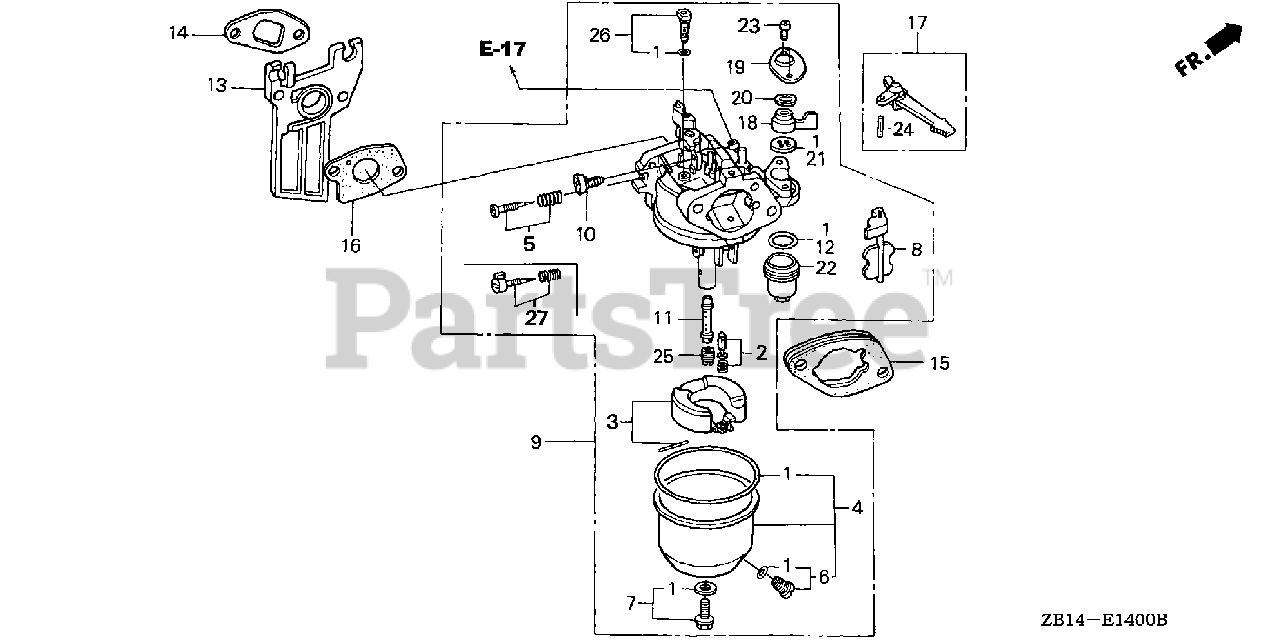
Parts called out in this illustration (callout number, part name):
1	GASKET SET
1	GASKET SET (CARBURETOR NO.)
2	VALVE SET, FLOAT
4	CHAMBER SET, FLOAT (CARBURETOR NO.)
5	SCREW SET, PILOT
6	SCREW SET, DRAIN (CARBURETOR NO.)
7	SCREW SET
9	CARBURETOR ASSY. (N/A: SEE COMPONENTS)
9	CARBURETOR ASSY.
10	SCREW, THROTTLE STOP
11	NOZZLE, MAIN (NOT AVAILABLE)
12	GASKET, FUEL STRAINER CUP
13	INSULATOR, CARBURETOR
14	GASKET, INSULATOR
15	SPACER, CARBURETOR
16	GASKET, CARBURETOR
17	LEVER, CHOKE (STD)
18	LEVER, VALVE
19	PLATE, LEVER SETTING
20	SPRING, PETCOCK LEVER (CARBURETOR NO.)
21	GASKET, PETCOCK (CARBURETOR NO.)
22	CUP, FUEL STRAINER
23	SCREW, PAN (3X8)
23	SCREW, PAN (3X8) (CARBURETOR NO.)
24	PIN, SPRING (2X12)
25	JET, MAIN (#62) (CARBURETOR NO.)
25	JET, MAIN (#65)
25	JET, MAIN (#68)
26	JET SET, PILOT (#35)
